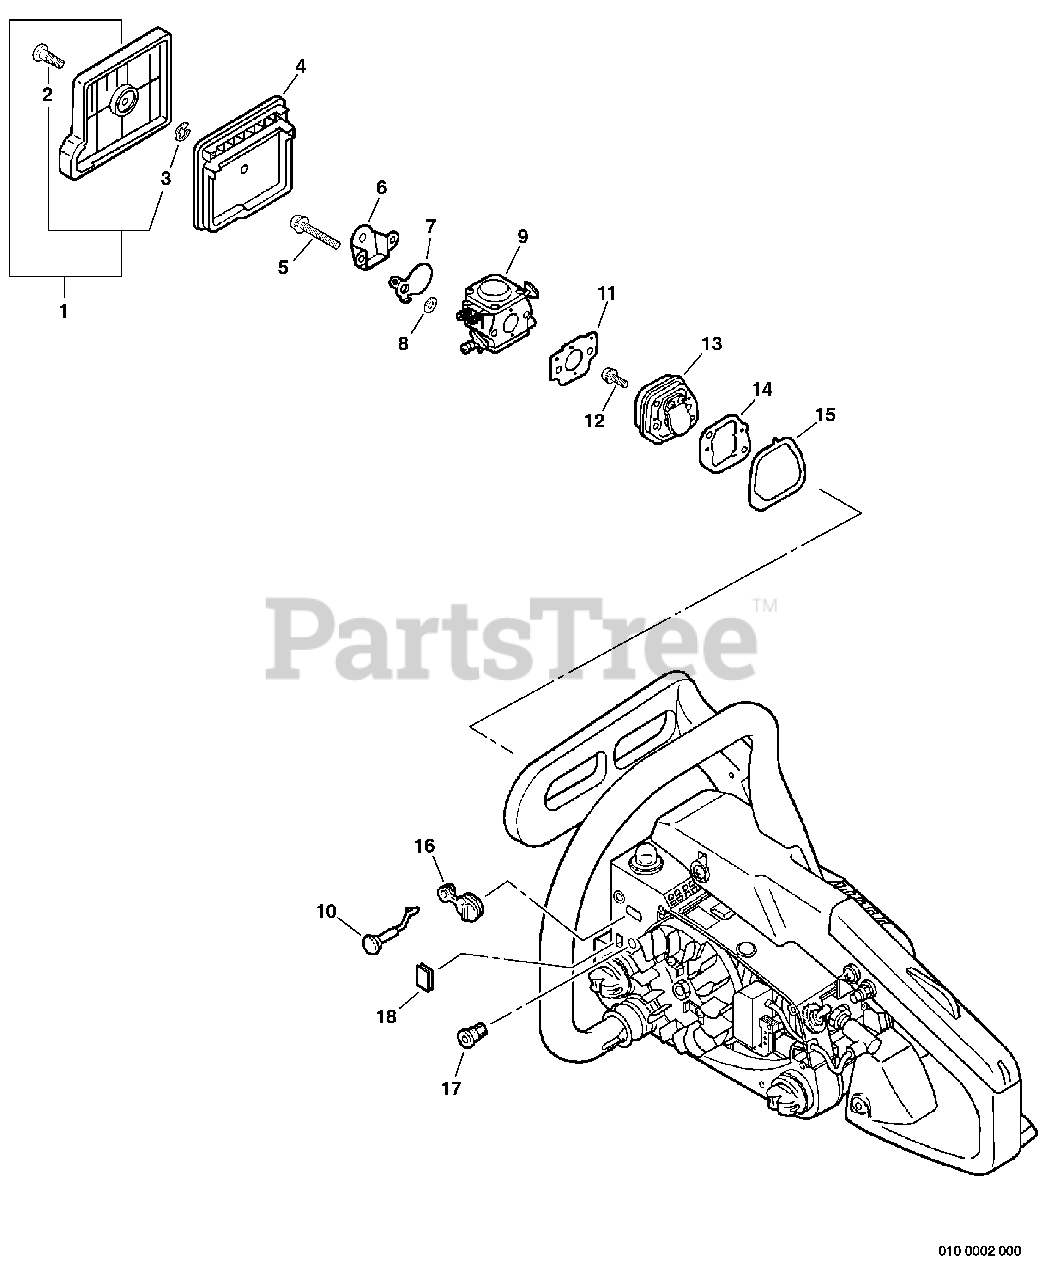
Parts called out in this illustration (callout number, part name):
1	AIR FILTER COVER ASSY
2	THUMBSCREW
3	RING, RETAINING - 4
4	FILTER, AIR
5	SCREW - 5X45
6	PLATE, PREVENT
7	SHUTTER, CHOKE
8	WASHER
9	CARBURETOR WT-589A
10	ROD, CHOKE
11	GASKET, INTAKE
12	SCREW - 5X18
13	INSULATOR KIT
14	GASKET, INTAKE
15	SEAL
